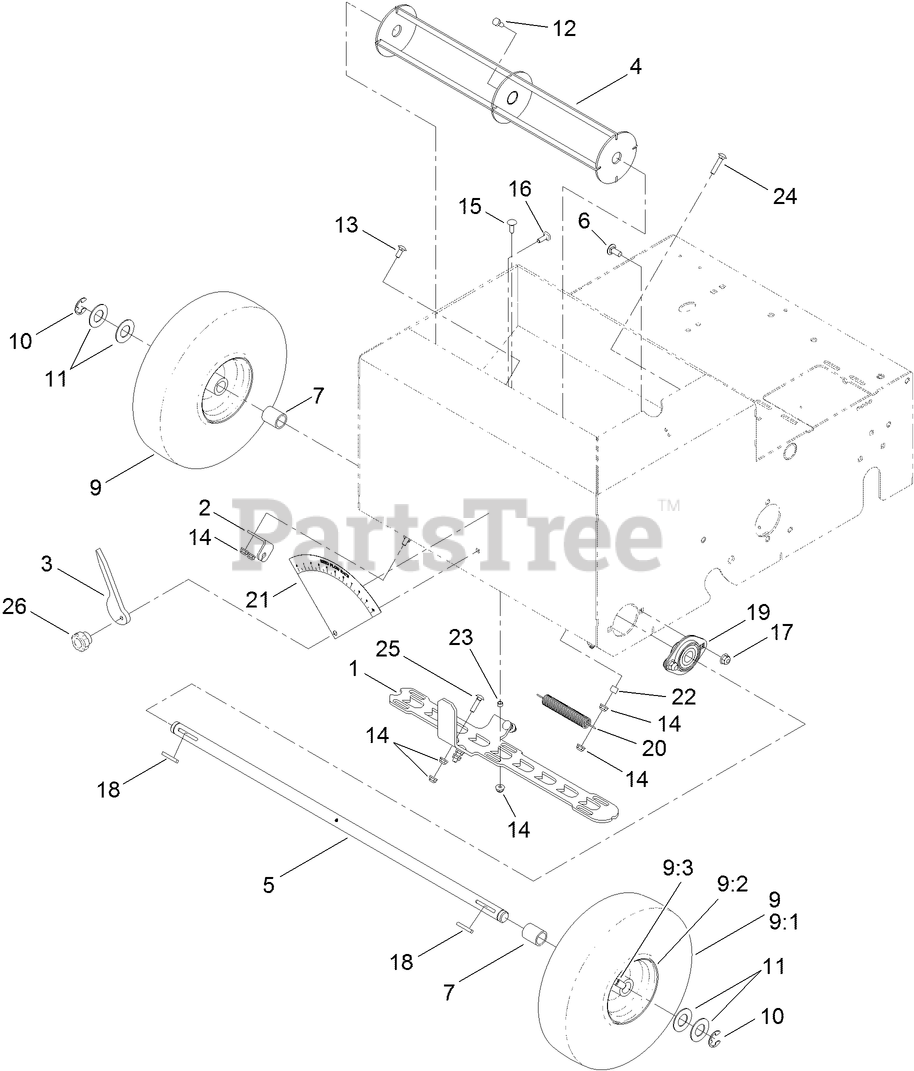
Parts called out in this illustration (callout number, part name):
1	GATE-SEED
2	BRACKET-SEED FLOW
3	GAUGE-SEED FLOW
4	MIXER
5	AXLE-FRONT
6	SCREW-CARR
7	Spacer
9	WHEEL ASM
9:2	WHEEL-RIM
9:3	VALVE
10	E-RING
11	WASHER-FLAT
12	SCREW-HH
13	SCREW-CARR
14	NUT-HF
15	BOLT-CARR
16	BOLT-CARR
17	NUT-HF, NI
18	KEY-SQUARE
19	BEARING
20	SPRING-EXTENSION
21	DECAL-RATE, FLOW
22	SPACER
23	SPACER
24	SCREW-CARR
25	SCREW-CARR
26	KNOB-CHUTE
